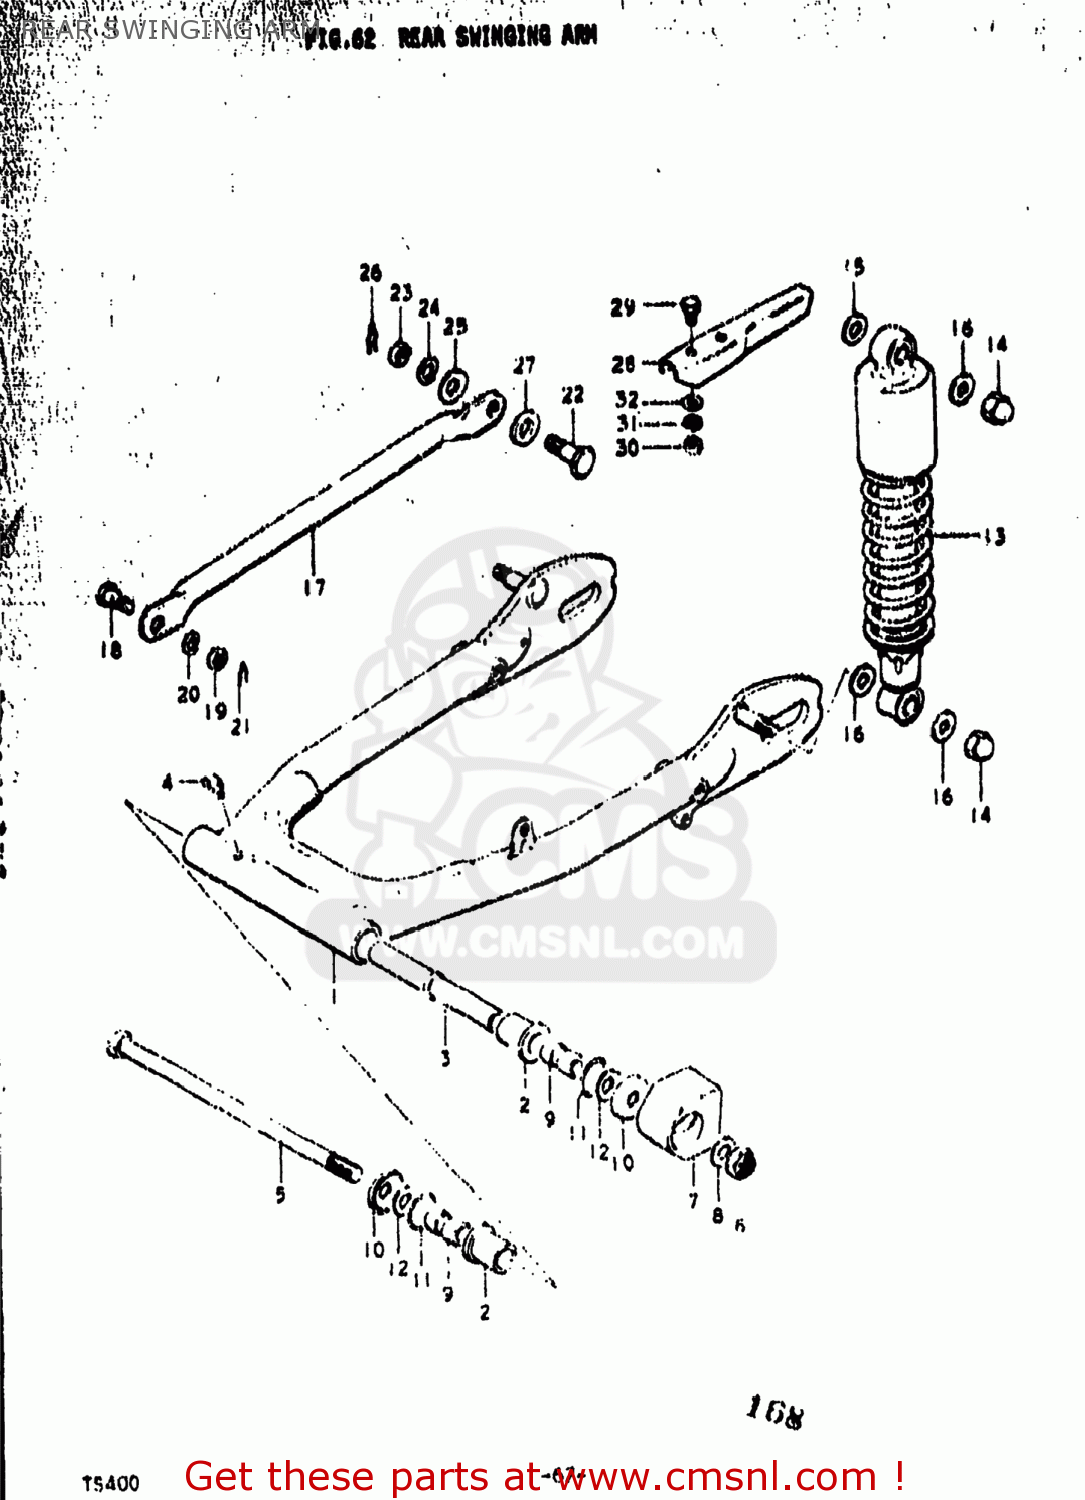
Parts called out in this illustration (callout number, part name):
1	SWING ARM ASSEMBLY,REAR
2	BUSH
3	SPACER,SWING ARM,CENTER
4	NIPPLE,GREASE
5	SHAFT,REAR SWING ARM
6	NUT
7	BUFFER,CHAIN TOUCH DEFLECTOR
8	WASHER
9	SPACER
10	COVER
11	O RING(D:3,ID:29.5)
12	WASHER(14.5X29X2.3)
13	ABSORBER ASSEMBLY,REAR SHOCK
14	NUT
15	WASHER
16	WASHER
17	TORQUE LINK,REAR
18	BOLT(8X22.5)
19	NUT
20	LOCK WASHER
21	CLIP
22	BOLT
23	NUT
24	LOCK WASHER
25	WASHER,LOCK
26	CLIP
27	WASHER
29	BOLT
30	NUT
31	LOCK WASHER
32	WASHER
